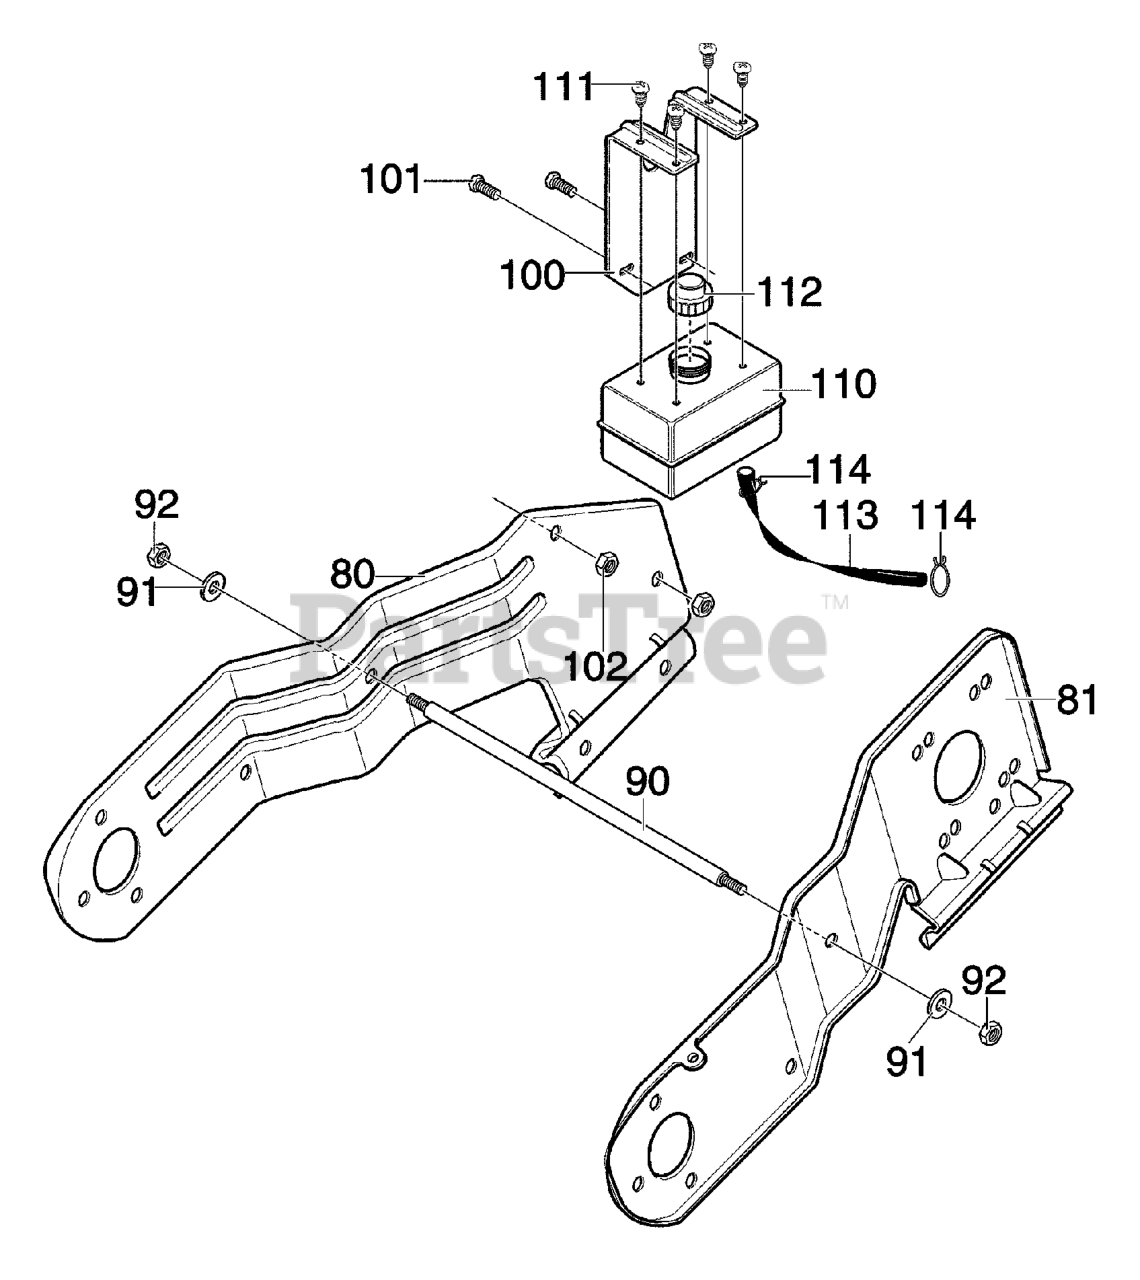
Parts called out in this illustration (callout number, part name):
80	FRAME SIDE SUPPORT RH
81	FRAME SIDE SUPPORT LH
90	ROD, SUPPORT
91	WASHER
92	NUT, 3/8-16
100	BRACKET, GAS TANK
101	SCREW, 1/4-20X.75
102	NUT, 1/4-20
110	TANK, FUEL
112	CAP, GAS-RED
113	TUBING 11.50 IN.
114	CLAMP, FUEL LINE
